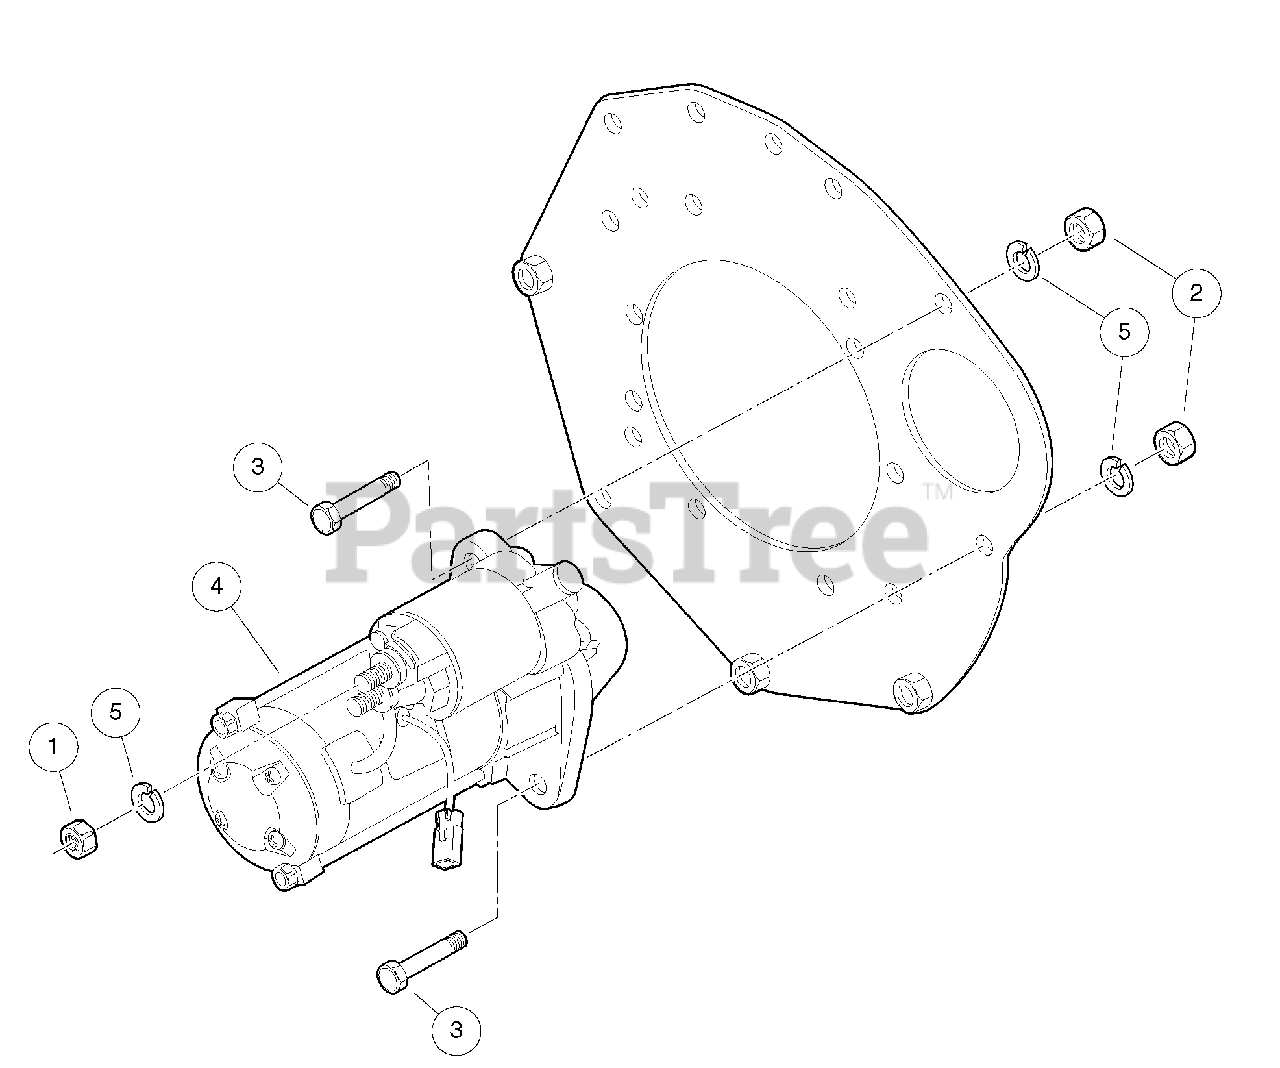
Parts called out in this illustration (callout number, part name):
1	Nut, D722, Starter
2	Nut, M8, Plate
3	Bolt, M8 X 1.25 X 28
4	Motor, Starter
5	Washer, Spring, D722, Starter
